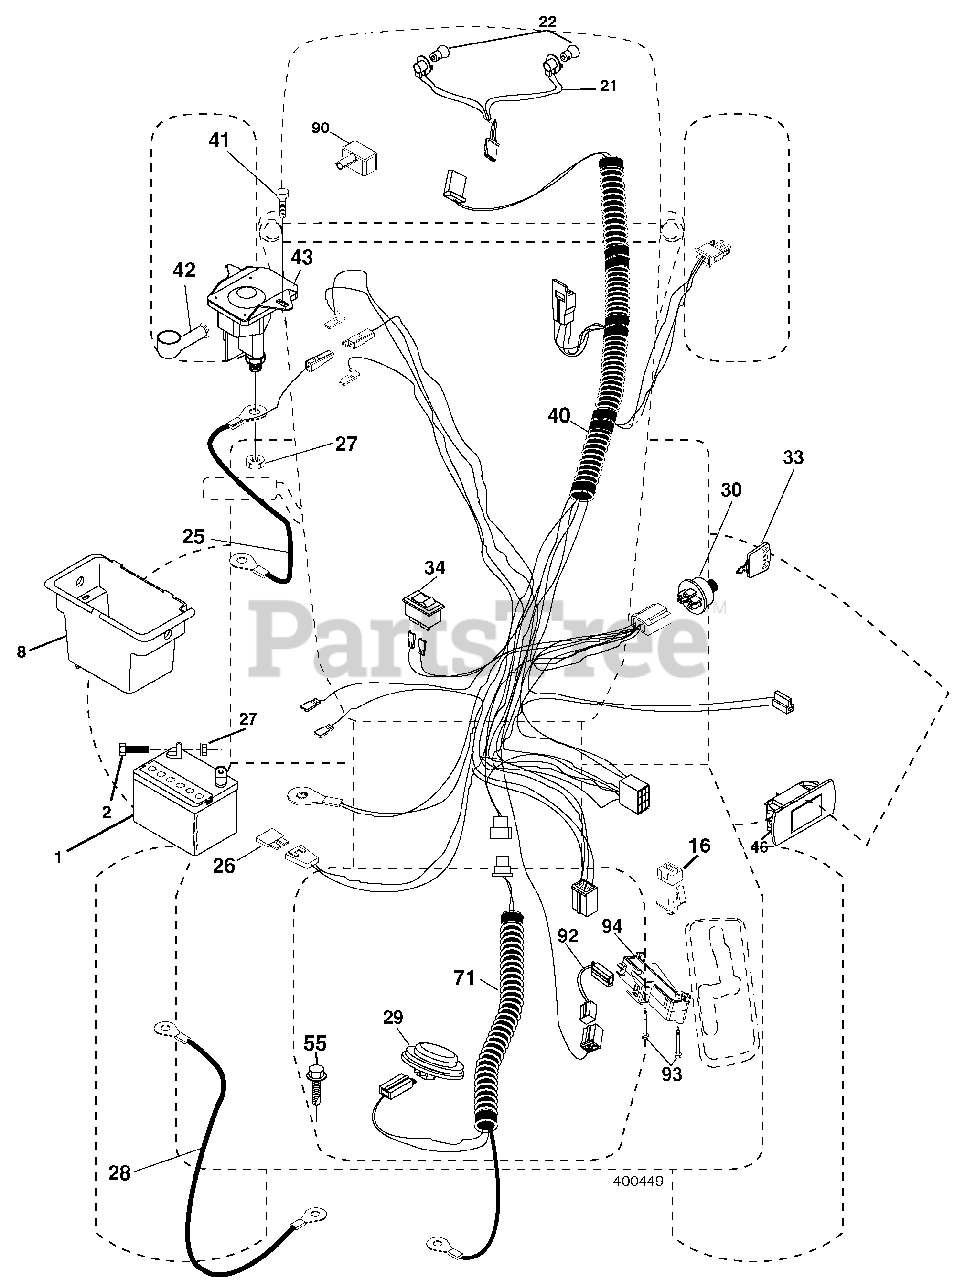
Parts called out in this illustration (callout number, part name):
1	Battery
2	Bolt Hex Head 1/4-20 x 3/4
8	Box Battery
16	Switch Interlock Push-In
21	Harness Socket Light W/4152J
22	Bulb Light
25	Cable Starter
26	Fuse
27	Nut Keps Hex 1/4-20 unc
28	Cable, Ground
29	Switch, Seat
30	Switch, Ign
33	Key, Ignition
34	Switch Light / Reset
40	Harness Ign.
41	Screw Thd Cut 1/4-20 x 1/2
42	Cover, Terminal
43	Solenoid
46	Gauge Hourmeter
55	Screw Thdrol 5/16-18 x 3/4 TYTT
71	Harness Ign. Dash
90	Cover Terminal Battery
92	Harness Pigtail
93	Screw Plastite 10-14 x 2.0
94	Module Reverse ROS
